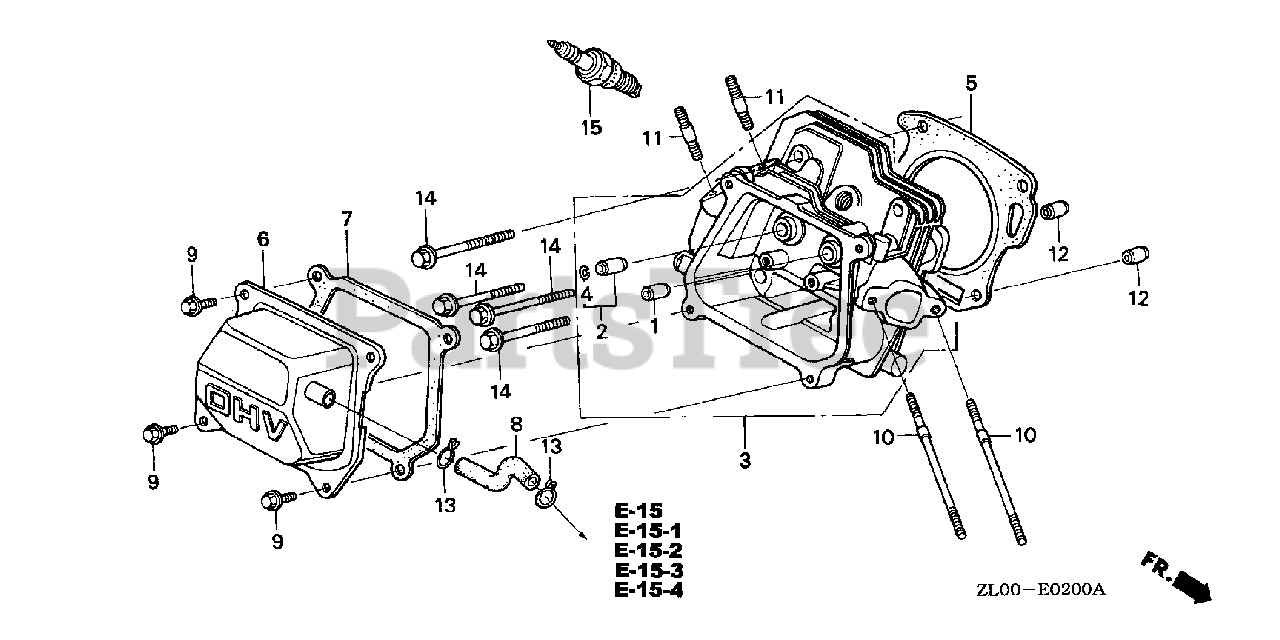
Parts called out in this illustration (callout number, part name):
1	GUIDE, VALVE (OS)
2	GUIDE, EX. VALVE (OS)
3	CYLINDER HEAD
4	CLIP, VALVE GUIDE
5	GASKET, CYLINDER HEAD
6	COVER, HEAD
7	GASKET, CYLINDER HEAD COVER
8	TUBE, BREATHER
9	BOLT, FLANGE (6X12) (CT200)
10	BOLT, STUD (6X109)
11	BOLT, STUD (8X32)
12	PIN A, DOWEL (10X16)
14	BOLT, FLANGE (8X60)
15	SPARK PLUG (BPR6ES) (NGK)
15	SPARK PLUG (W20EPR-U) (DENSO)
